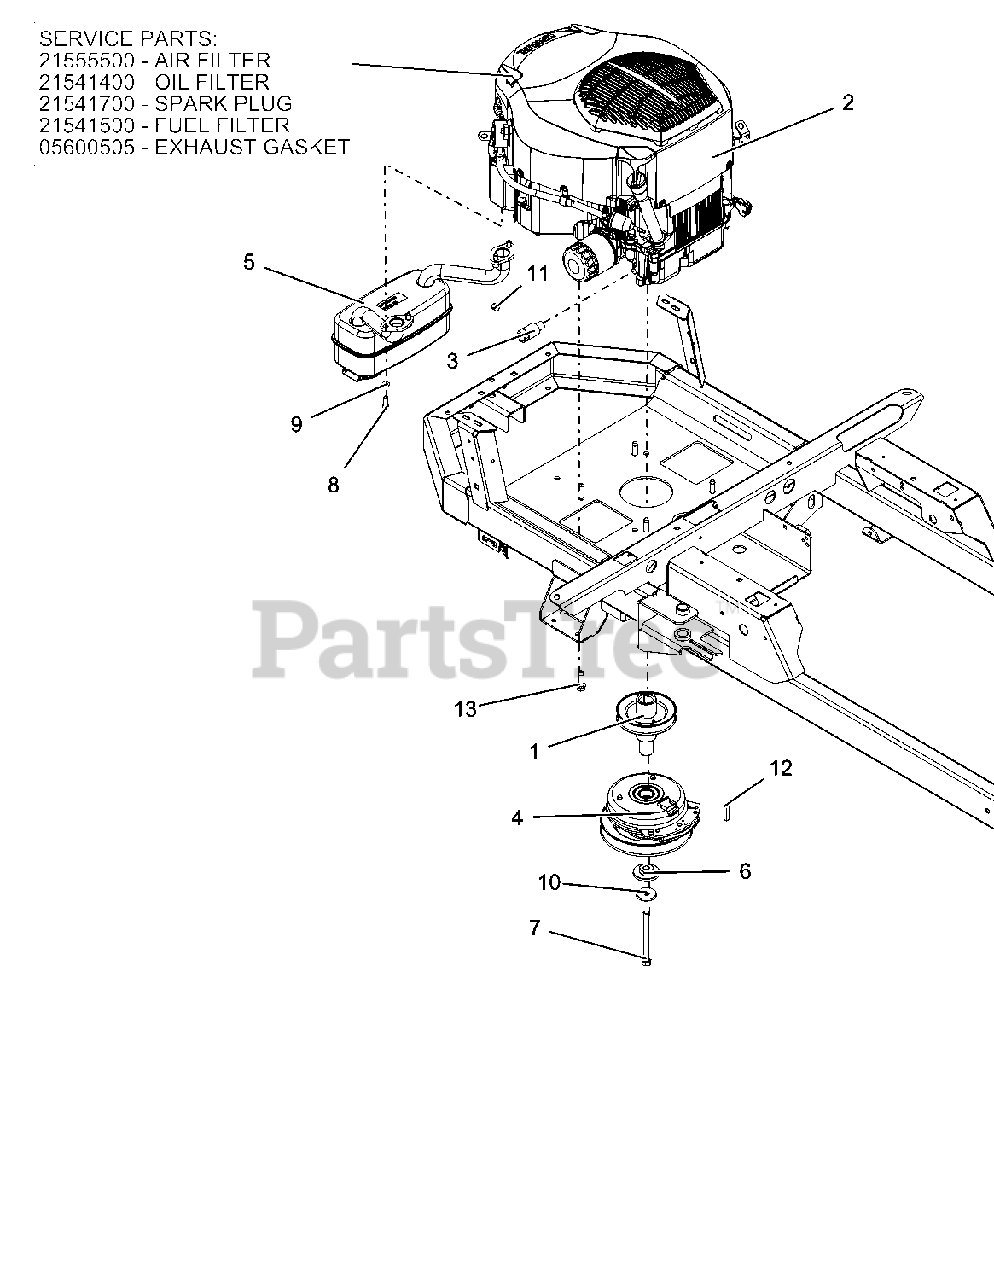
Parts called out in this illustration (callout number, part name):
1	WLDMT, DRIVE SHEAVE-X
2	PLUG, SPARK
2	FILTER, FUEL
2	FILTER, ENGINE OIL (COURAGE)
2	GASKET, MUFFLER COURAGE TWIN
2	ENGINE, KOHLER 22HP TWIN
2	AIR CLEANER, KOHLER
3	DRAIN, OIL
4	CLUTCH,105FTLB MONOPOLE 6.83"
5	MUFFLER, KOHLER TWIN
6	BSHG-FLG .469X1.06X.574X2.0
7	BLT-HEX.438-20X4.5GR8YZ NYTORQ
8	SCR-CAP .31-18X.75 S/HD
9	@WSHR-LK .31X.078 REG YWZC
10	WASHER, 7/16" SPRING DISK
11	NUT-LK-TOP M8-1.25 YWZC
12	KEY-SQ .25 X 1.25 X .25 SAE
13	@SCR-TAP .38-16X1.25 HWH TR YZ
